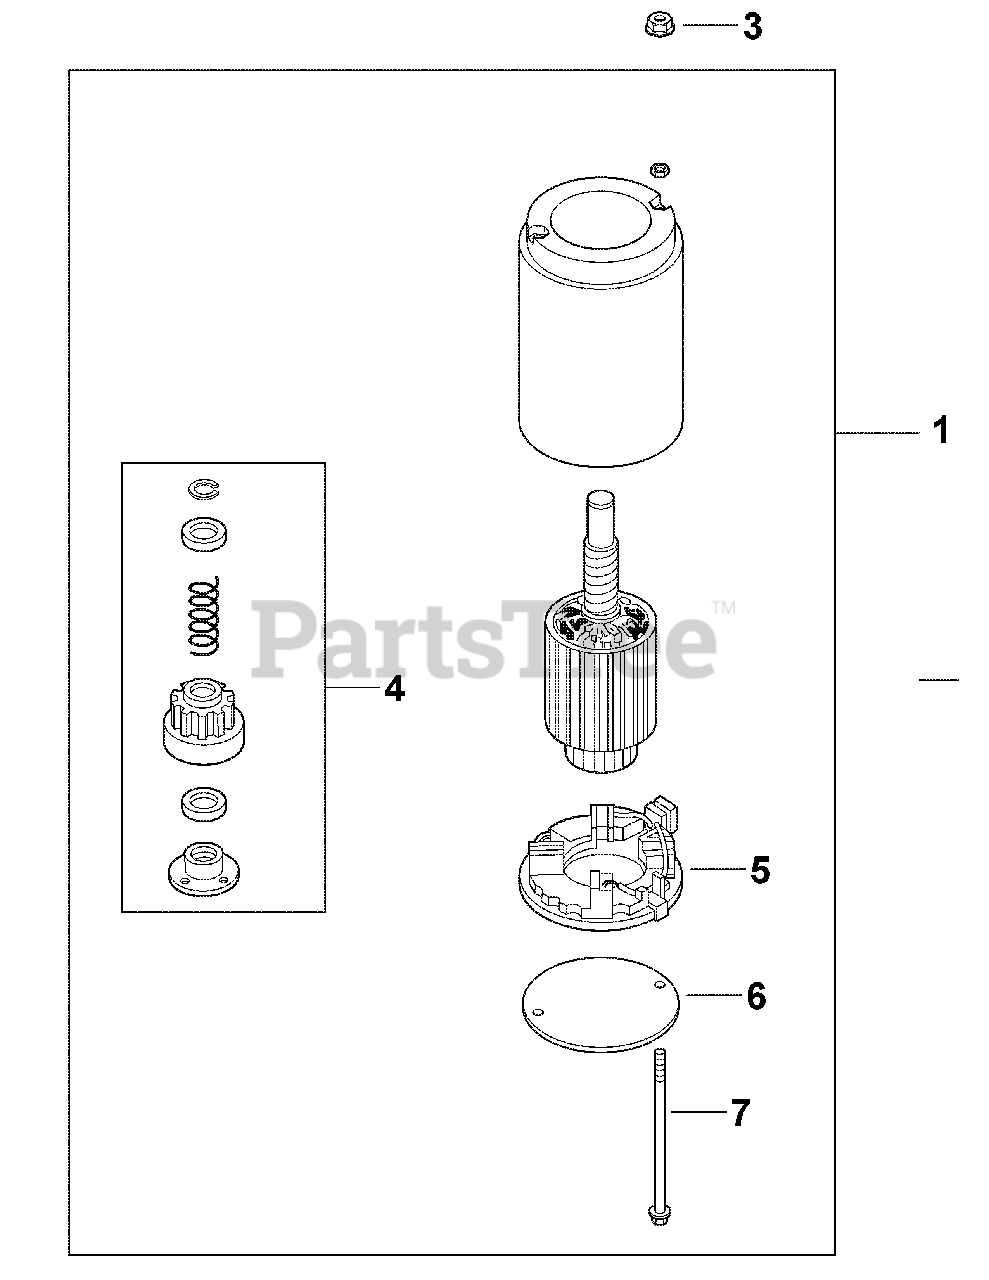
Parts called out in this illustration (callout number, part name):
1	Starter Assembly (Inc. 4-7)
3	Free Spinning Flg. Nut, #10-24
4	Drive Kit (J.E.)
6	Drive End Cap (J.E.)
